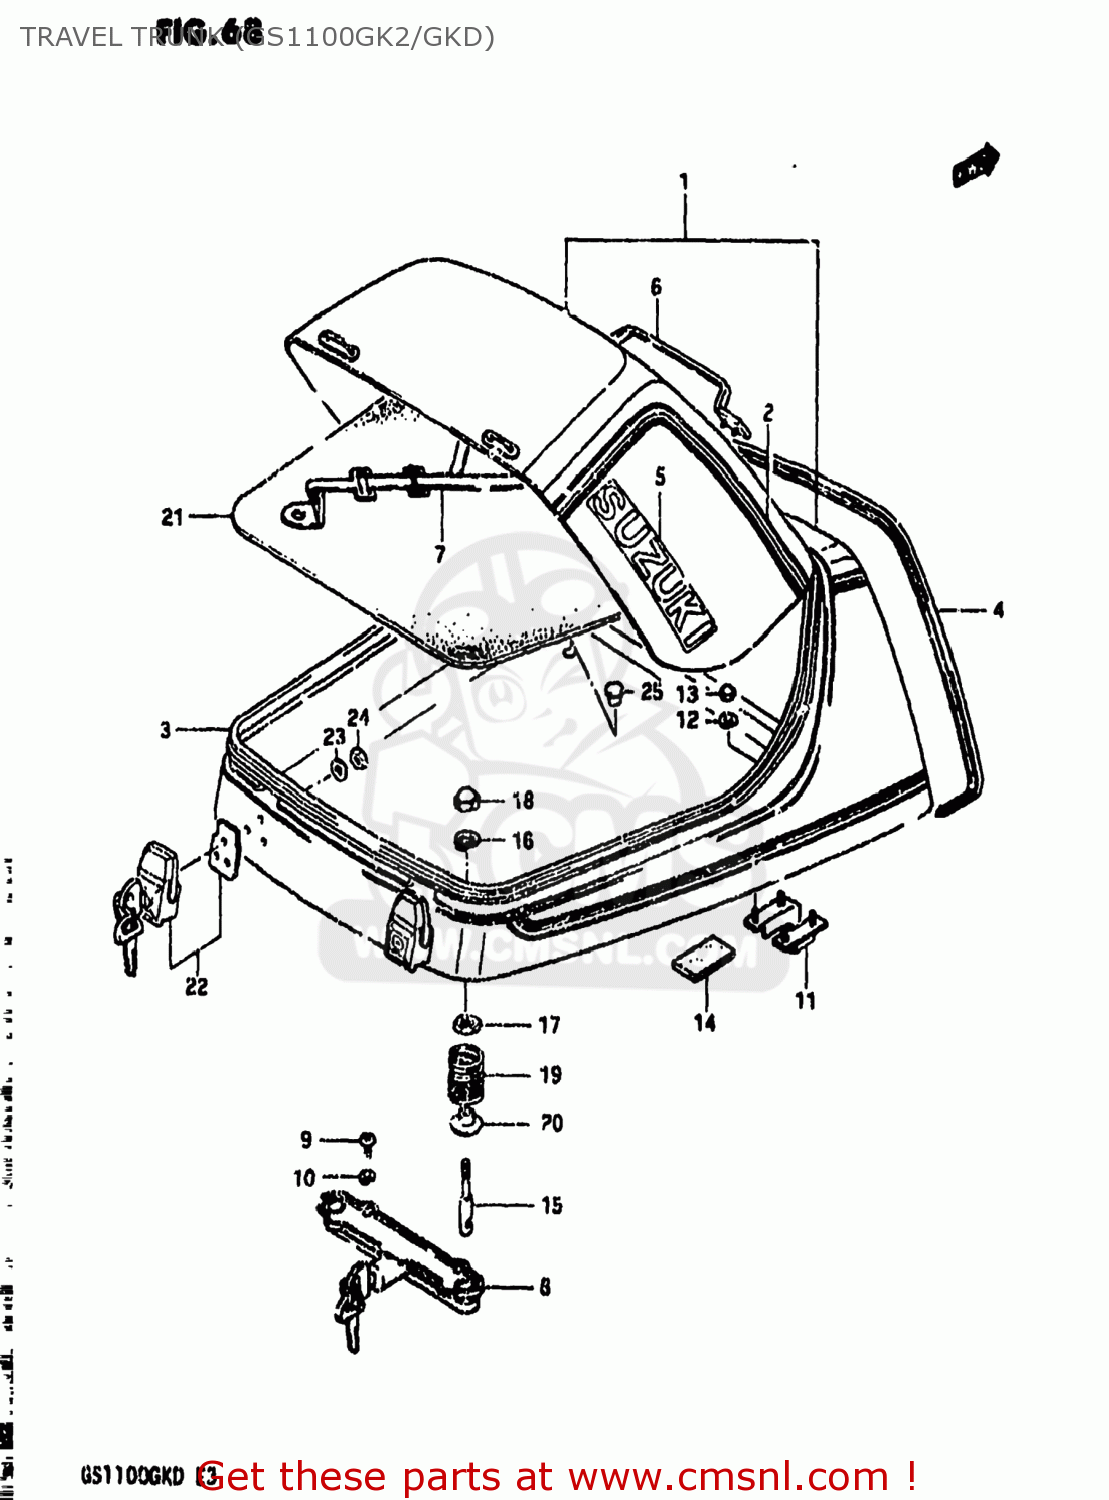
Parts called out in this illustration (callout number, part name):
1	TRAVEL TRUNK (BROWN/BROWN)
2	TAPE SET,COWLING BODY
3	SEAL,TRAVEL TRUNK
4	MOLDING,TRAVEL TRUNK
5	EMBLEM
6	BAND SET
7	BAND SET
8	LOCK,TRAVEL TRANK
9	SCREW 6X12
10	LOCK WASHER
11	HOOK COMP TRAV TRUNK
12	LOCK WASHER
13	NUT
14	CUSHION TRAVEL TRUNK
15	LOCK BOSS TRAV TRUNK
16	WASHER,LOCK,8.
17	NUT 8MM
18	NUT
19	GUIDE,TRAVEL TRUNK SPRING
20	GUIDE,TRAVEL TRUNK SPRING
21	CUSHION TRAVEL TRUNK
22	LOCK,TRANK LID
23	WASHER
24	NUT 4MM
25	PLUG(OD:14)
